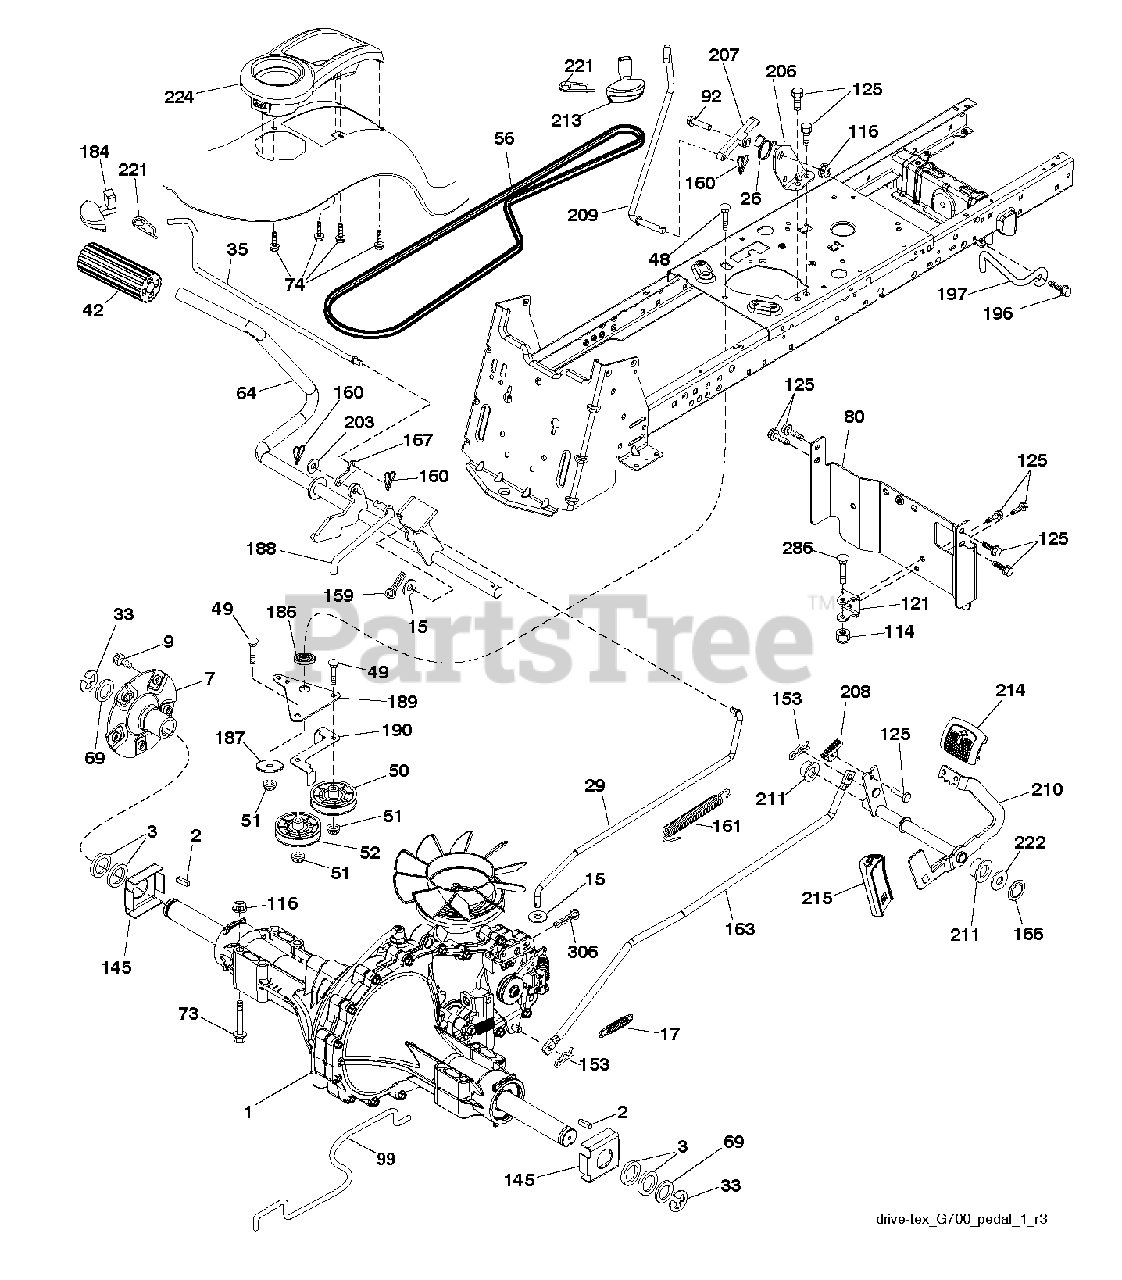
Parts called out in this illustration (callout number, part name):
7	HUB.ASM.WHEEL.REAR.23"TEX
9	HUB BOLT
17	SPRING.BRAKE.HG3000/3500
26	SPRING.RETURN.CRUISE
35	ROD.BRAKE.PARTK.HUSQ.TEX
42	PEDAL COVER T
48	BOLT.3/8-16X1.50
49	BOLT
50	IDLER.FLAT.910.OFFSET
51	NUT LOCK FLG 3/8-16 UNC
52	IDLER.V-GROOVE.910.OFFSET
56	DRIVE BELT, LTH & YTH TRACTORS
64	SHAFT.ASM.PEDAL.BRK.CNTR
73	Flghd Hex Bolt, 5/16-18 X 3 Gr 5
74	SCREW.HI-LO.CONSOLE
80	STRAP.TORQUE.YT.G700
92	BOLT
99	SPRING.BYPASS.YT.G700
114	NUT.71038.31-18.HEX.NYLOCK
116	NUT LOCK HEX FLANGE 5/16-18
121	BRACKET STRAP TORQUE
125	SCREW
145	Flange Axle Washer, Hg-3000
153	RETAINER M
159	COTTER PIN
160	RETAINER CLIP
161	SPRING, RETURN LT
163	ROD PEDAL CONTROL
167	LATCH.BRAKE.SPRING
184	HANDLE.PARKG.BRK.HUSQ/PRED.667
186	SPACER.RETAINER
187	WASHER 12/32X2X10GA
188	LINK.CLUTCH.GROUND.DRIVE
189	BELLCRANK.GROUND.DRIVE.TRAPPED
190	KEEPER BELLCRANK ROUND DRIVE
196	SCREW 3/8-16X1
197	BRKT.ANIT-ROTATION.CLU
203	WASHER
206	BRKT.MOUNT.LATCH.CRUIS
207	LATCH.CONTROL.CRUISE
208	GEAR.SECTOR.CONTROL.CR
209	ROD.CONTROL.CRUISE.GT.
210	ROCKER.ASM.PEDAL.CONTR
211	BEARING.NYLON
213	KNOB.CONTROL.CRUSIE.HU
214	PAD PEDAL FORWARD
215	PEDAL.REVERSE.TEX.GT.4
221	RETAINER.SPRING.CLIP.H
222	WASHER 21/32 X 1-1/4 X 10 GA.
224	CONSOLE.TOOLBOX.PCH.ERGO.BLACK
225	KEEPER.TA.YT.G700
226	BRACKET.MOUNT.TORQUE.K66.TG
286	BOLT.5/16-18X2.5
306	PIN COTTER
